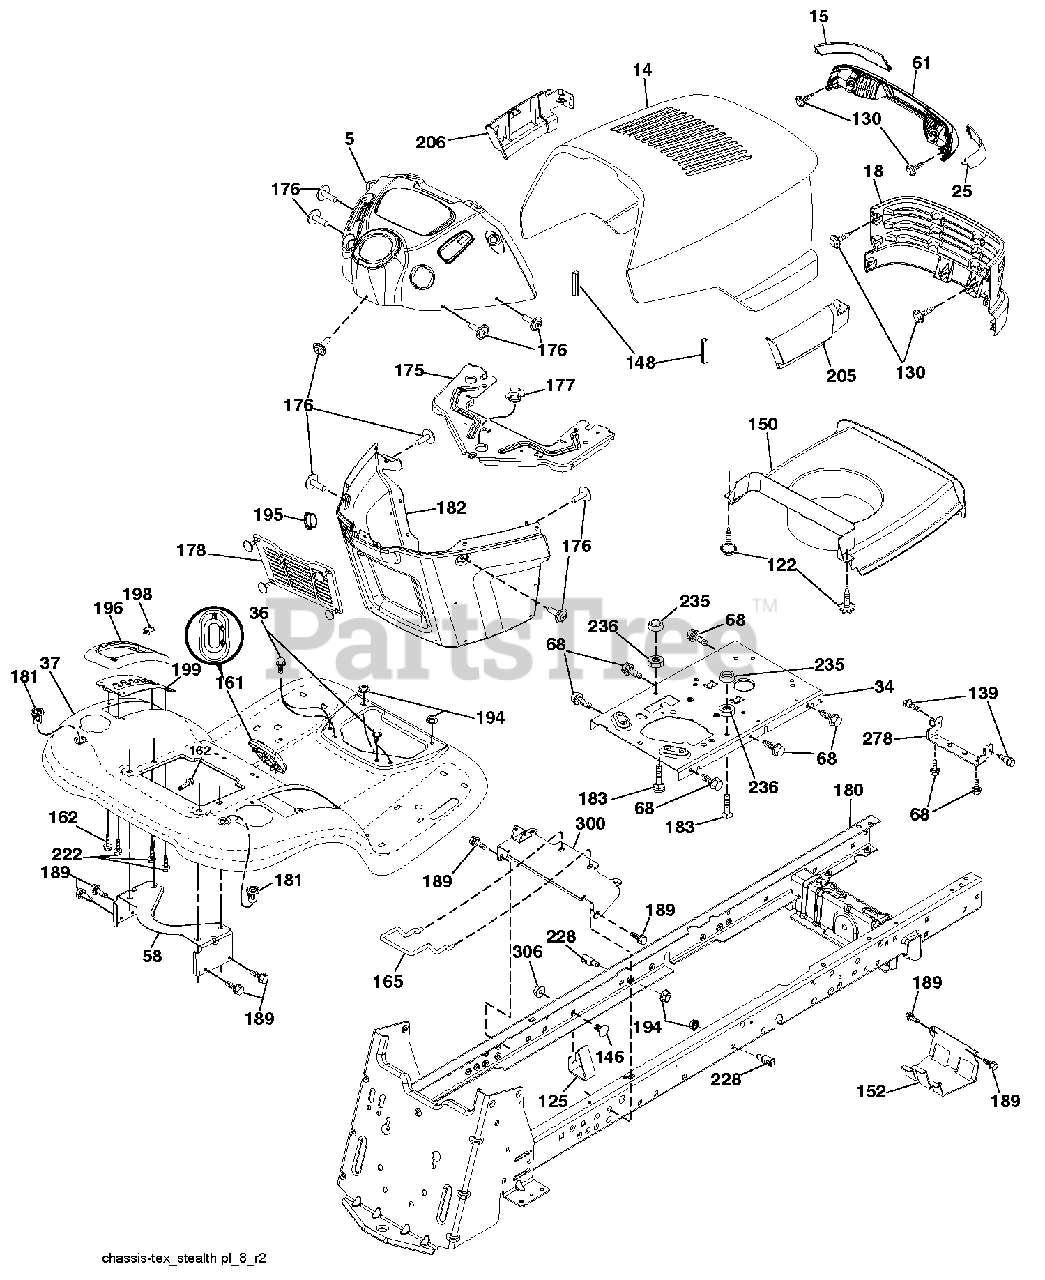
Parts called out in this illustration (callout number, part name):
5	DASH.STEALTH.EL.LIFT.RND.428
15	LENS LH
18	GRILLE.STEALTH.GT.BLACK
25	LENS RH
37	FENDER.BLUE.TXGT.ERGO.SD.FILL
58	BRKT.SUPPORT.FNDR/TANK
68	SCREW LT
122	SCREW.WSHD.HEX10-32X5/8
130	SCREW.#10 X 0.750.BOS THREAD
148	EXTRUSION BUMPER
150	DUCT HEAT HOOD
152	SHIELD BROWNING
161	CONSOLE.FUEL.WINDOW.STGT.BLACK
162	SCREW.HI-LO.CONSOLE
165	SUPPORT.TANK.REAR.B/TE
175	CROSSMEMBER.
176	SCREW.#10-24X5/8.RN.QU
177	BUSHING,STEERING
178	CARGO.ASM.NET.DASH.LOWER
180	CHASSIS.GT.SLOPED.DRAWBAR.
182	DASH.LOWER.
183	BOLT.5/16-18X1-1/4 FULL THD
194	NUT LOCK HEX FLANGE 5/16-18
196	CONSOLE.ASM.DECK.
198	INDICATOR.DECK.LIFT.RED
199	PLATE.DECK.LIFT.ELECTRIC
205	SKIRT.GRILLE.STEALTH.RH
206	SKIRT.GRILLE.STEALTH.LH
222	SCREW.1/4-20X5/8
228	STUD.FASTNER.W/ANTI-ROTATE
235	SPACER FENDER
236	NUT.CENTERLOCK.5/16-
278	BRKT.HOOD/MUFF.STEALTH
300	BRACKET.ASM.LIFT.ELECTRIC
